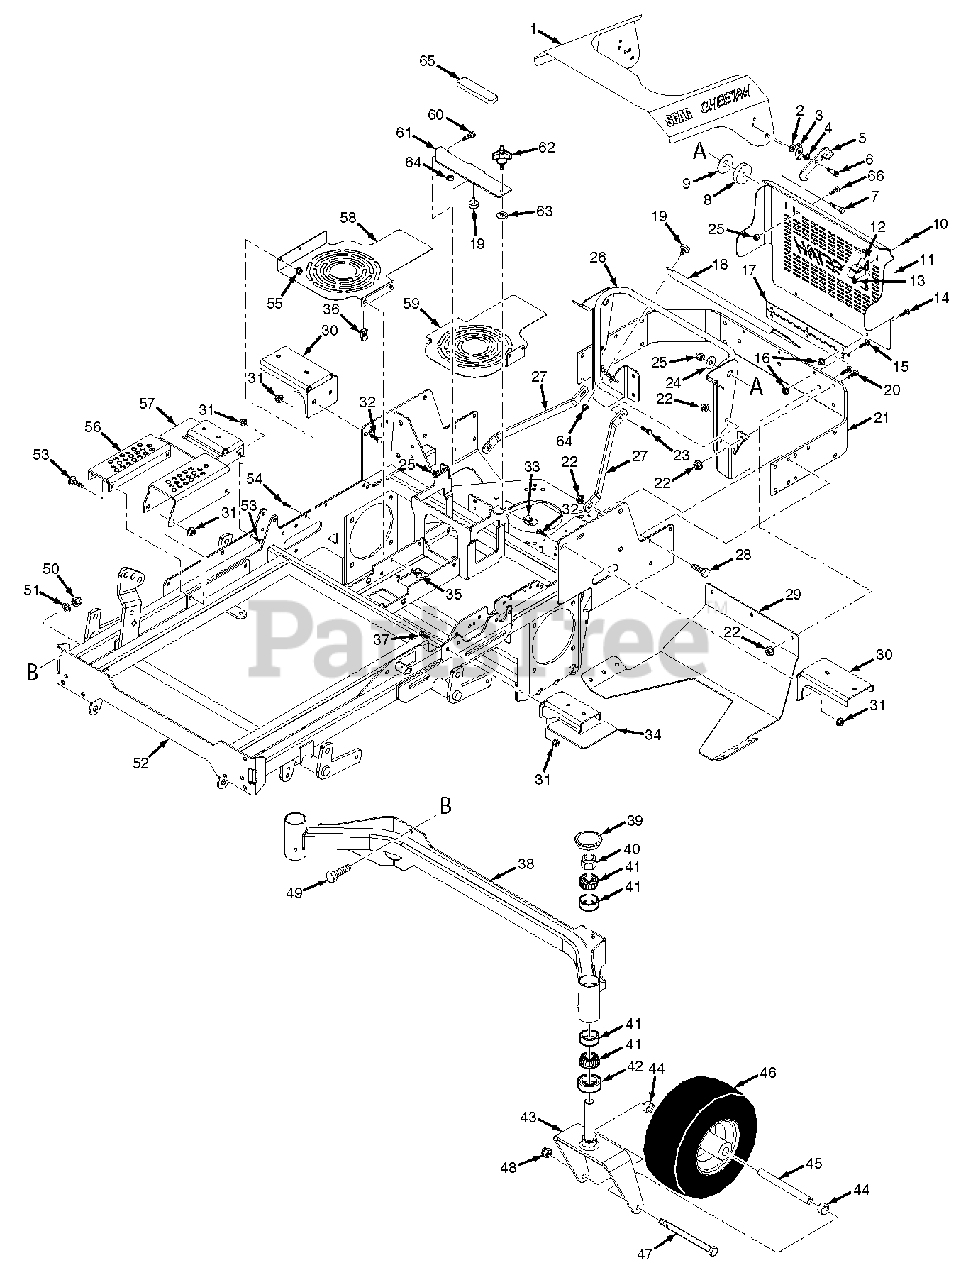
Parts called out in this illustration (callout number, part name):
1	Hood Assembly w/Decals
1	Hood Assembly w/Decals - Kohler ECV860
2	Flatwasher, 3/8-.406 x .812 x .065
3	Lock, Hood Latch
4	Spring, Hood Latch
5	Latch, Hood
6	Bolt, Shoulder
7	Bolt, Hex Head 3/8-16 x 1-3/4"
8	Spacer, Hood
9	Disc, Anti-Friction
10	Screw, #8-32 x 1/2"
11	Belt Guard, Rear
11	Belt Guard, Rear - Kohler
12	Spring Clip
13	Nut, Elastic Stop #8-32
14	Bolt, Carriage 1/4-20 x 1/2"
15	Bolt, Carriage 1/4-20 x 3/4"
16	Nut, Serrated Flange 1/4-20
17	Hinge, Belt Cover
18	ROPS Heatshield
18	ROPS Heatshield - Kohler
19	Bumper, Rubber
20	Button Head Capscrew, Torx 3/8-16 x 1"
21	Bumper, Rear
22	Nut, Serrated Flange 3/8-16
23	Bolt, Hex Head 3/8-16 x 1"
24	Flatwasher, 3/8-.406 x 1.5 x 7 Ga.
25	Nut, Elastic Stop 3/8-16
26	Mount Weldment, Hood
26	Mount Weldment, Hood - Kohler
27	Brace, Hood Support
28	Bolt, Hex Head 3/8-16 x 1-1/4"
29	SCZ Skid Plate, Kawasaki FX
29	SCZ Skid Plate, Kohler
30	Mounting Bracket, Fuel Tank Rear
31	Nut, Serrated Flange 5/16-18
32	Bolt, Carriage 5/16-18 x 3/4"
33	U-Nut, 3/8-16
34	Mounting Bracket, Fuel Tank Front
35	Bolt, Hex Head 1/4-20 x 1"
36	U-Nut, 1/4-20
37	Bolt, Carriage 5/16-18 x 3/4"
38	Caster Support Weldment, 61V
38	Caster Support Weldment, 72V
39	Cap, Grease
40	Nut, Elastic Stop 1"-14
41	Bearing w/Race
42	Seal, 2" OD x 1.625 Bore
43	Yoke Weldment
44	Spacer, Caster Wheel
45	Sleeve, Caster Wheel
46	Caster Wheel Assy.
46	Bearing
46	Grease Fitting
47	Bolt, Hex Head 1/2-13 x 9-1/2"
48	Nut, Elastic Stop 1/2-13
49	Bolt, Hex Head 7/16-14 x 1-1/4"
50	Nut, Elastic Stop 7/16-14
51	Lockwasher, 7/16-" Spring
52	Mainframe Assy. w/Decals
53	Bolt, Hex Head 5/16-18 x 1"
53	Lockwasher, 5/16" Spring
54	Bolt, Hex Head 1/4-20 x 3/4"
55	Nut, Serrated Flange 1/4-20
56	Adjustment Bracket, Lower Cut Height
57	Adjustment Bracket, Upper Cut Height
58	Fan Cover, RH
59	Fan Cover, LH
60	Bolt, Hex Head 3/8-16 x 1"
61	Cover, Battery Box
62	Knob w/Stud
63	Nut, Push-On 3/8"
64	Nut, Serrated Flange 5/16-18
65	Pad, Rubber
66	Capscrew, Button Head 3/8-16 x 1-1/4"
